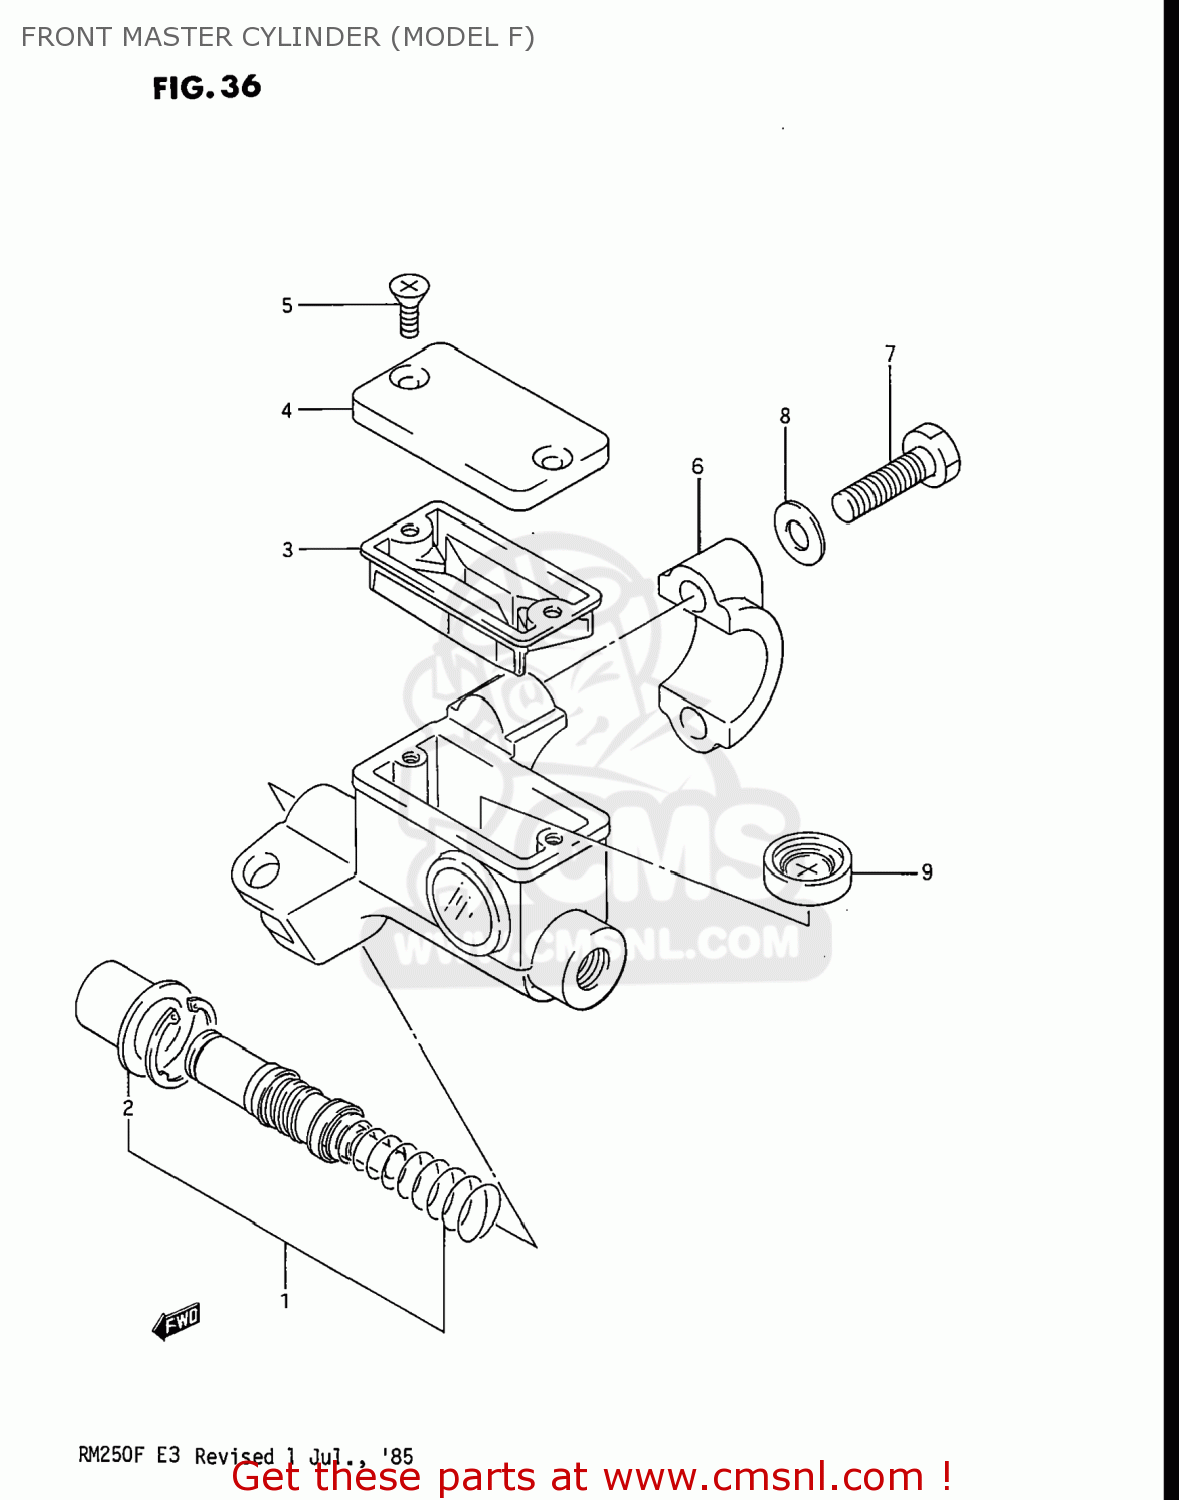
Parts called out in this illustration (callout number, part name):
1	PISTON/CUP SET,FR MASTER
2	BOOT
3	DIAPHRAGM
4	CAP
5	SCREW
6	HOLDER,MASTER CYLINDER
7	BOLT
8	WASHER
9	SEPARATOR
